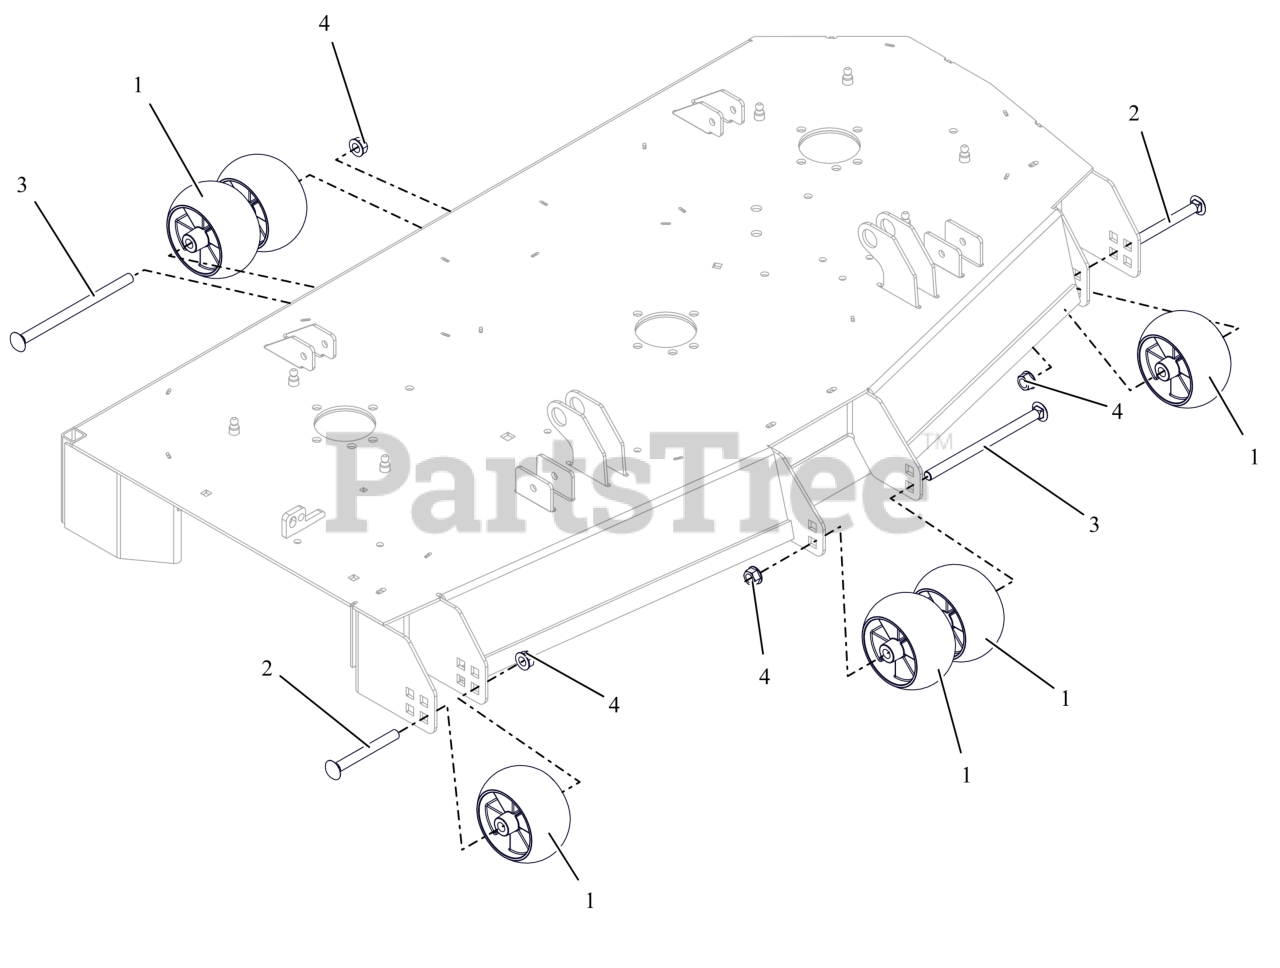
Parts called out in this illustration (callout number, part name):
1	WHEEL, ANTI SCALP - 5X3 CTR W/RIBS
2	BLT,RHNS .50-13X4.50 G5 ZCC NS
3	BLT,RHSN .50-13X8.00 G5 ZCC NS
4	NUT-LK-CTR-FLG .500-13 GG ZCC
